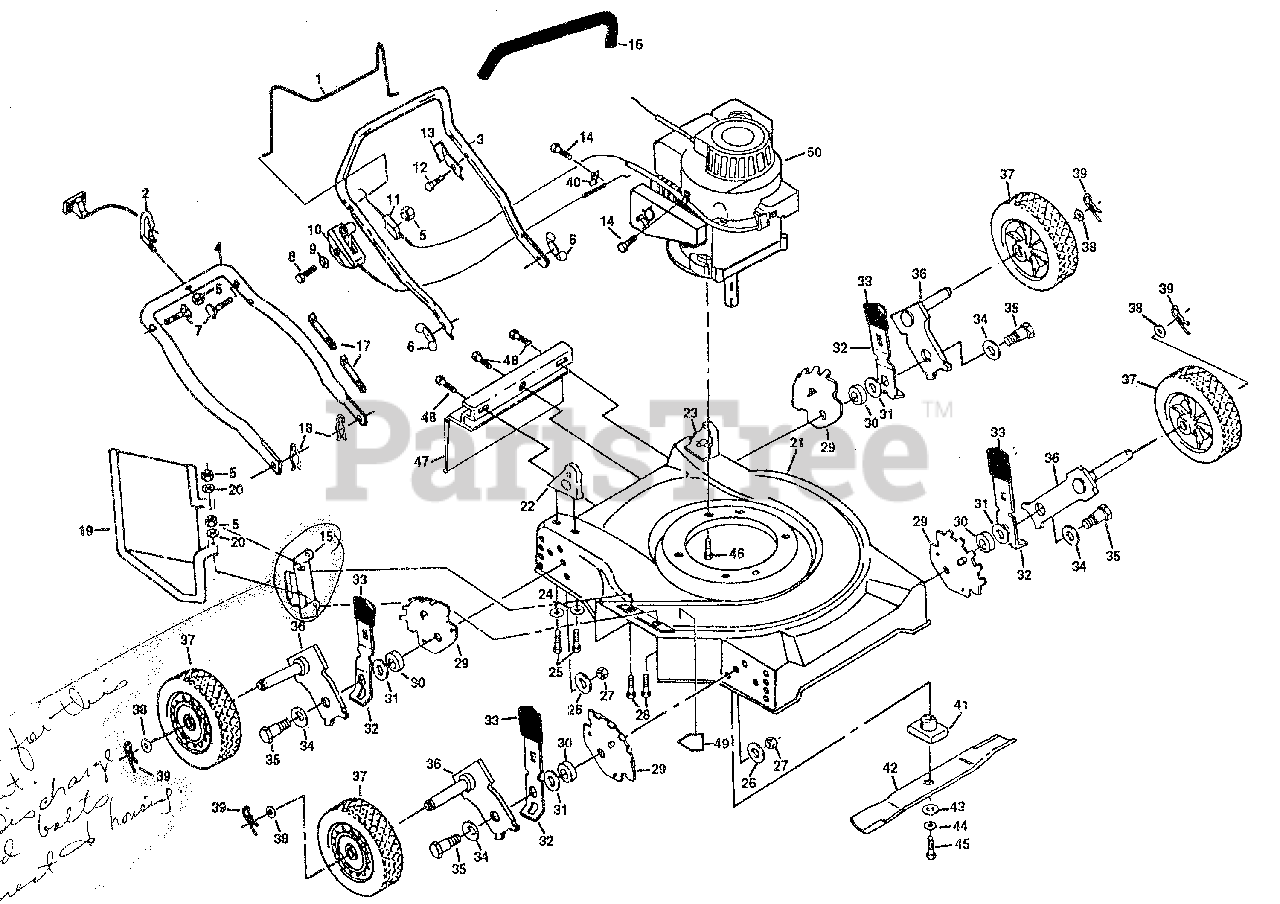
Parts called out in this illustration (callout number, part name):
1	Control Bar
2	Rope Guide
3	Upper Handle
4	Lower Handle
5	Locknut 1/4-20
7	Handle Bolt
8	Machine Screw 1/4-20 x 2-1/8
9	Washer 9/32x5/8x1/16
10	Throttle Control
11	Engine Zone Control Cable
12	Hex Washer Head Tapping Screw #10-24x1/2
13	Up-Stop Bracket
14	Thread Rolling Screw
15	Housing Bracket
16	Handle Grip
17	Wire Tie
18	Hairpin Cotter
19	Discharge Guard Assembly
20	Washer
21	Lawn Mower Housing Kit
22	Handle Bracket Assembly
23	Handle Bracket Assembly
24	Washer 5/16
25	Thread Cutting Screw 5/16-18 x 3/4
26	Flat Washer 3/8
27	Locknut 3/8-16
28	Hex Head Bolt
29	Wheel Adjuster Bracket
30	Spacer
31	Washer .39x1.25x.09
32	Selector Spring
33	Selector Knob
34	Belleville Washer 1/2
35	Shoulder Bolt 3/8-16
36	Axle Arm Assembly
37	Wheel & Tire Assembly 7.0 x 1.5
39	Retainer Clip
40	Cable Clamp
41	Blade Adapter
42	20" Blade
43	Hardened Washer
44	Helical Lockwasher 3/8
45	Hex Head Screw 3/8-24 x 1-3/8
46	Hex Head Thread Rolling Screw 3/8-16 x 1-1/8
47	Rear Skirt
48	Hex Washer Head Tapping Screw #10-24 x 1/2
49	Danger Decal
